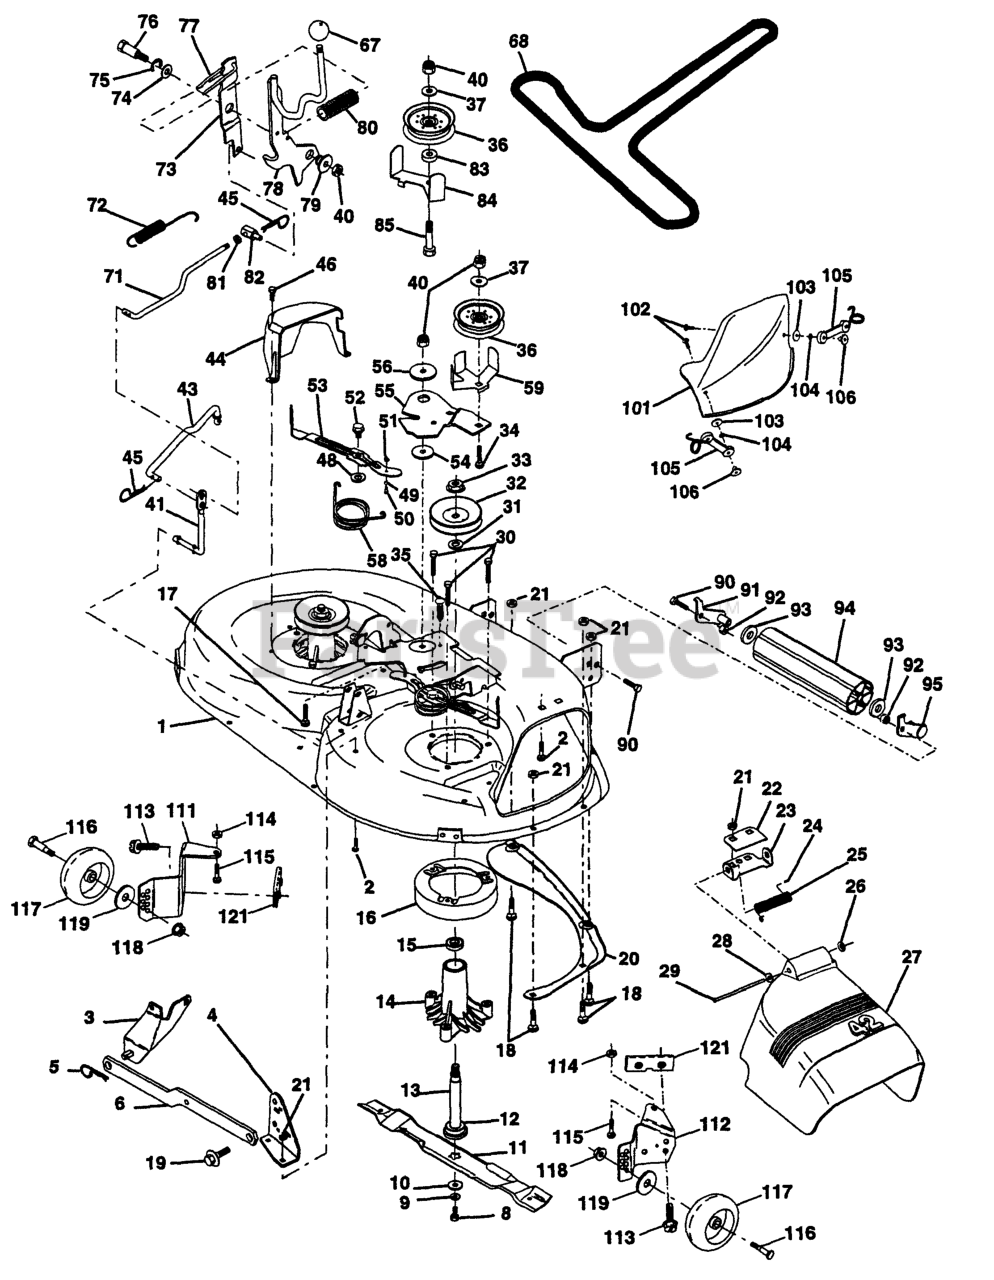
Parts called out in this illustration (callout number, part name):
1	DECK 42"
2	RP BOLT 5/16-18 X3/4 ZN/YEL GR
3	BRKT ASM SWAY BAR
4	BRKT DECK SW BAR
5	RETAINER-SPRNG RB
6	REAR SUSP ARM
8	BLADE BOLT
9	LOCKWASHER
10	WASHER.BLADE
11	BLADE.42".MULCH
12	BEARING.BALL.#6204.(MANDREL)
13	SHAFT ASM VENT
14	HOUSING.MANDREL.VENTED (MACHD)
16	STRIPPER
17	BOLT
18	BOLT
19	BOLT SHD 5/16-18
20	BAFFLE
21	LOCKNUT
22	STIFFENER BRACKET
23	DEFLECTOR BRACKET
24	CAP-SLEEVE LT
25	SPRING TORSION
26	NUT PUSH M
27	SHIELD.DEFLECTOR.MOWER.42".BLK
28	Washer 11/32 X 5/8 X 16 Ga
29	ROD.HINGE
30	SCREW
31	WASHER
32	MANDREL PULLEY
33	NUT
35	FASTENER.XMAS.TREE
36	FLAT IDLER PULLEY
37	WASHER
43	CLUTCH ROD
44	GUARD MANDREL LH BLACK
45	RETAINER M
46	SCREW.1/4-20X5/8
49	CAM FOLLOWER
52	BOLT.SHOULDER.5/16-18
53	ARM
54	HARDENED WASHER
55	IDLER ARM
56	SPACER RETAINER
59	GUARD, BELT
67	KNOB T (1/2-HOLE)
68	V-BELT TRIPATH
71	CLUTCH ROD
72	RETURN SPRING
73	ARM CLUTCH SECONDARY
77	KEEPER SPRING
78	CLUTCH ARM
79	BUSHING.FLANGE.E-RING.GROOVE
80	SPRING
81	NUT
82	TRUNNION.ADJUSTABLE.3/8-16
84	KEEPER BELT
85	BOLT
90	BOLT
91	BRACKET LH (A)
92	NUT
93	Washer 17/32 x 7/8 x 16 Ga.
94	NOSE ROLLER
95	BRACKET RH (B)
101	COVER MULCH 42"
102	SCREW
104	LOCKWASHER #10
105	LATCH ASSEMBLY
106	WELDNUT
111	BRACKET
112	BRACKET
113	SCREW.THDROL.5/16-18X3/4.TTY
114	NUT
115	BOLT.CARR.5/16-18X1/2
116	BOLT, SHOULDER
117	WHEEL GAGE DONUT
118	LOCKNUT
119	WASHER.5/16.FLAT.STE.STD.
120	Washer 17/32 x 15/16 x 12 Ga.
121	BRACKET.EXTRUDED.GAGE.WHEEL
